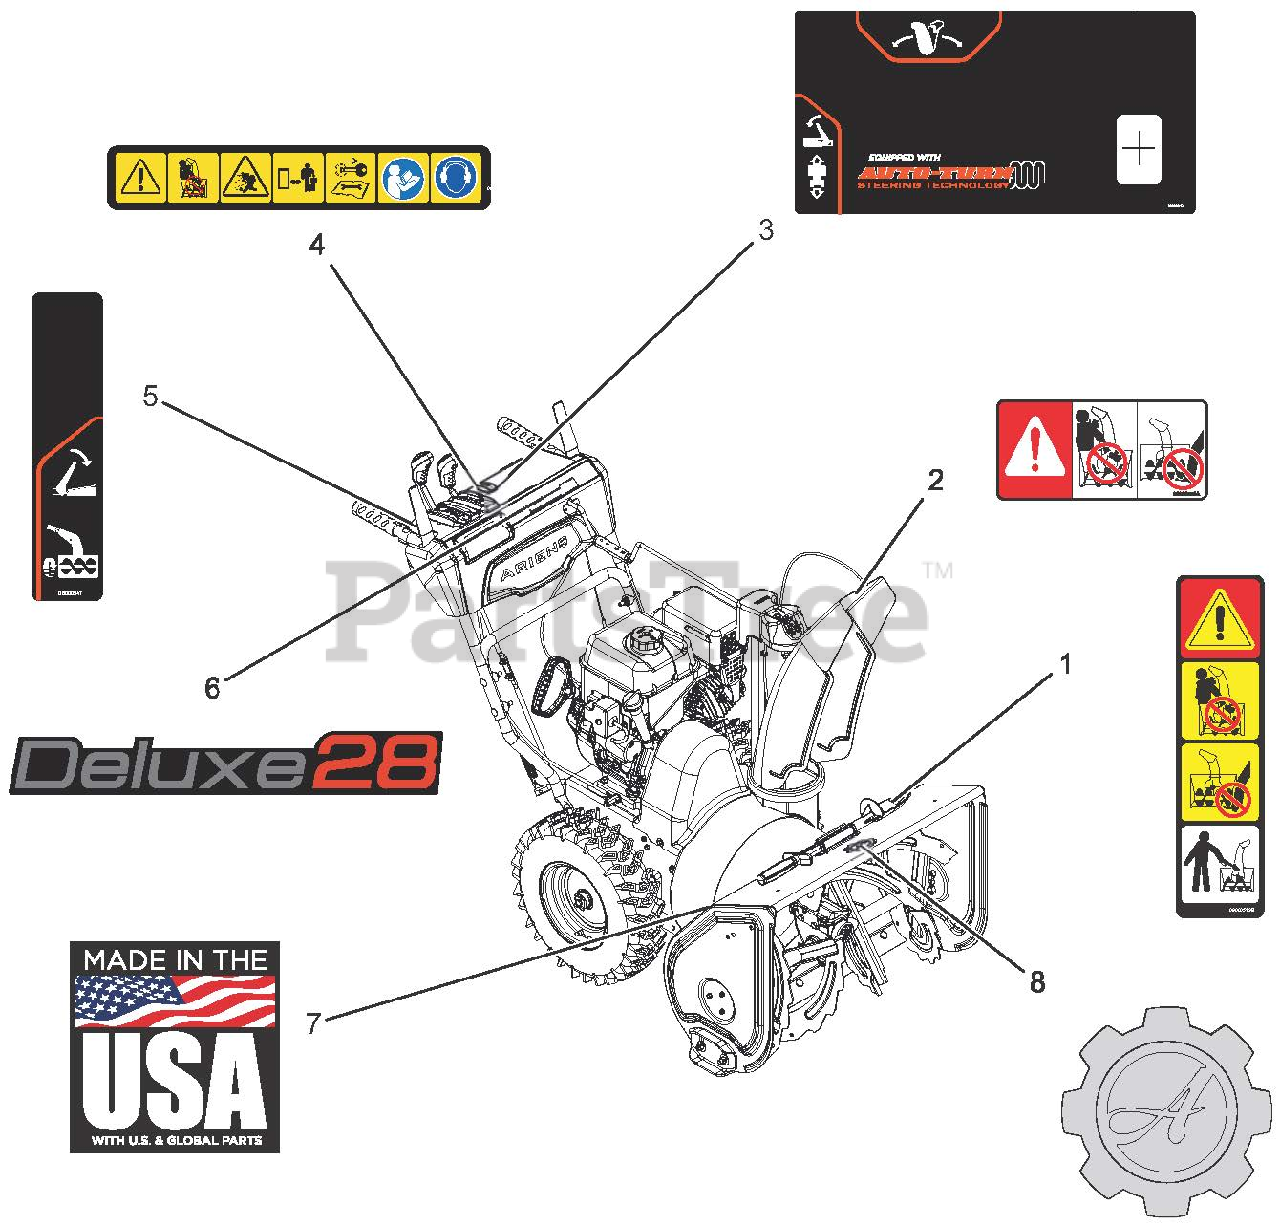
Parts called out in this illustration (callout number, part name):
1	DECAL, DANGER - ROTATING PARTS
2	DECAL, DANGER
3	DECAL,CONTROL-LG ID
4	DECAL,DASH - SAFETY
5	DECAL,CONTROL-RH CONTROL
6	DECAL, DASH - DELUXE 28
7	DECAL, MADE IN USA
8	DECAL, ARIENS-GEAR BADGE
